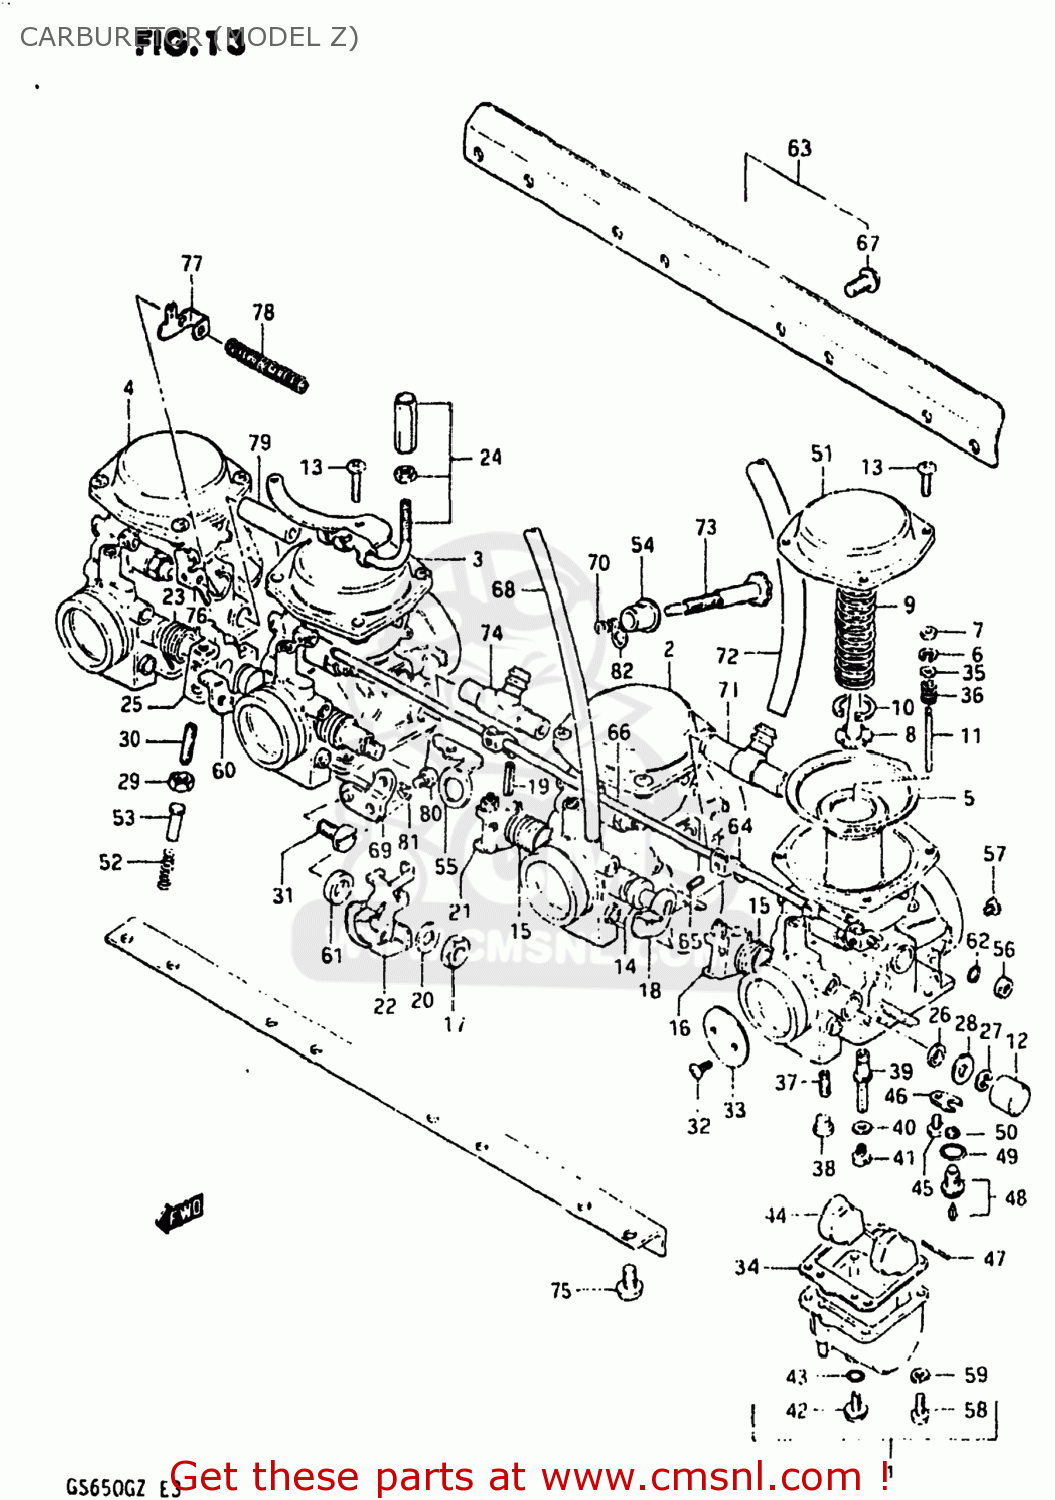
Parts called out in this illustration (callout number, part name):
1	CARBURETOR ASSEMBLY,LEFT
2	CARBURETOR ASSEMBLY
3	CARBURETOR ASSEMBLY
4	CARBURETOR ASSEMBLY
5	DIAPHRAGM
6	CLIP,NEEDLE
7	RING
8	HOLDER,GUIDE
9	SPRING
10	E RING
11	NEEDLE JET
12	CAP
13	SCREW
14	GASKET,THROTTLE SHAFT (NAS)
15	SPRING,THROTTLE SHAFT
16	SHAFT,THROTTLE
17	NUT 8MM
18	SHAFT,THROTTLE
19	PIN,THROTTLE SHAFT
20	WASHER
21	LEVER,THROTTLE SHAFT
22	LEVER ASSEMBLY,THROTTLE
23	SPRING,THROTTLE SHAFT
24	BRACKET,THROTTLE CABLE
25	SHAFT,THROTTLE
26	SEAL
27	E RING
28	GASKET,THROTTLE SHAFT (NAS)
29	NUT
30	SCREW
31	SCREW
32	SCREW
33	VALVE,THROTTLE (BUTTERFLY)
34	GASKET,FLOAT CHAMBER (NAS)
35	WASHER
36	SPRING
37	JET,PILOT(42.5)
38	PLUG,NEEDLE JET
39	JET,NEEDLE
40	WASHER,NEEDLE NOZZLE
41	JET,MAIN(110)
42	PLUG,DRAIN
43	GASKET (NAS)
44	FLOAT
45	SCREW 4X6
46	PLATE,NEEDLE VALVE FITING
47	PIN,FLOAT
48	VALVE ASSEMBLY,NEEDLE
49	O-RING,NEEDLE VALVE
50	FILTER
51	COVER,DIAPHRAGM
52	SPRING,THROTTLE SCREW
53	PIN,THROTTLE LEVER
54	BUSH
55	BRACKET,THROTTLE ADJUST
56	CAP,STARTER VALVE
57	JET
58	SCREW
59	LOCK WASHER
60	SHAFT,THROTTLE
61	WASHER
62	O RING
63	CARBURETOR ASSEMBLY
64	LEVER
65	SCREW
66	SHAFT,STARTER
67	SCREW
68	HOSE
69	BRACKET,THROTTLE ADJUST
70	SPRING
71	NIPPLE
72	HOSE
73	SCREW
74	NIPPLE,CARBURETOR
75	SCREW 6X12
76	LEVER,CHOKE CABLE
77	PLATE,CHOKE CABLE
78	SPRING,CHOKE CABLE
79	NIPPLE
80	SCREW
81	LOCK WASHER
82	WASHER
